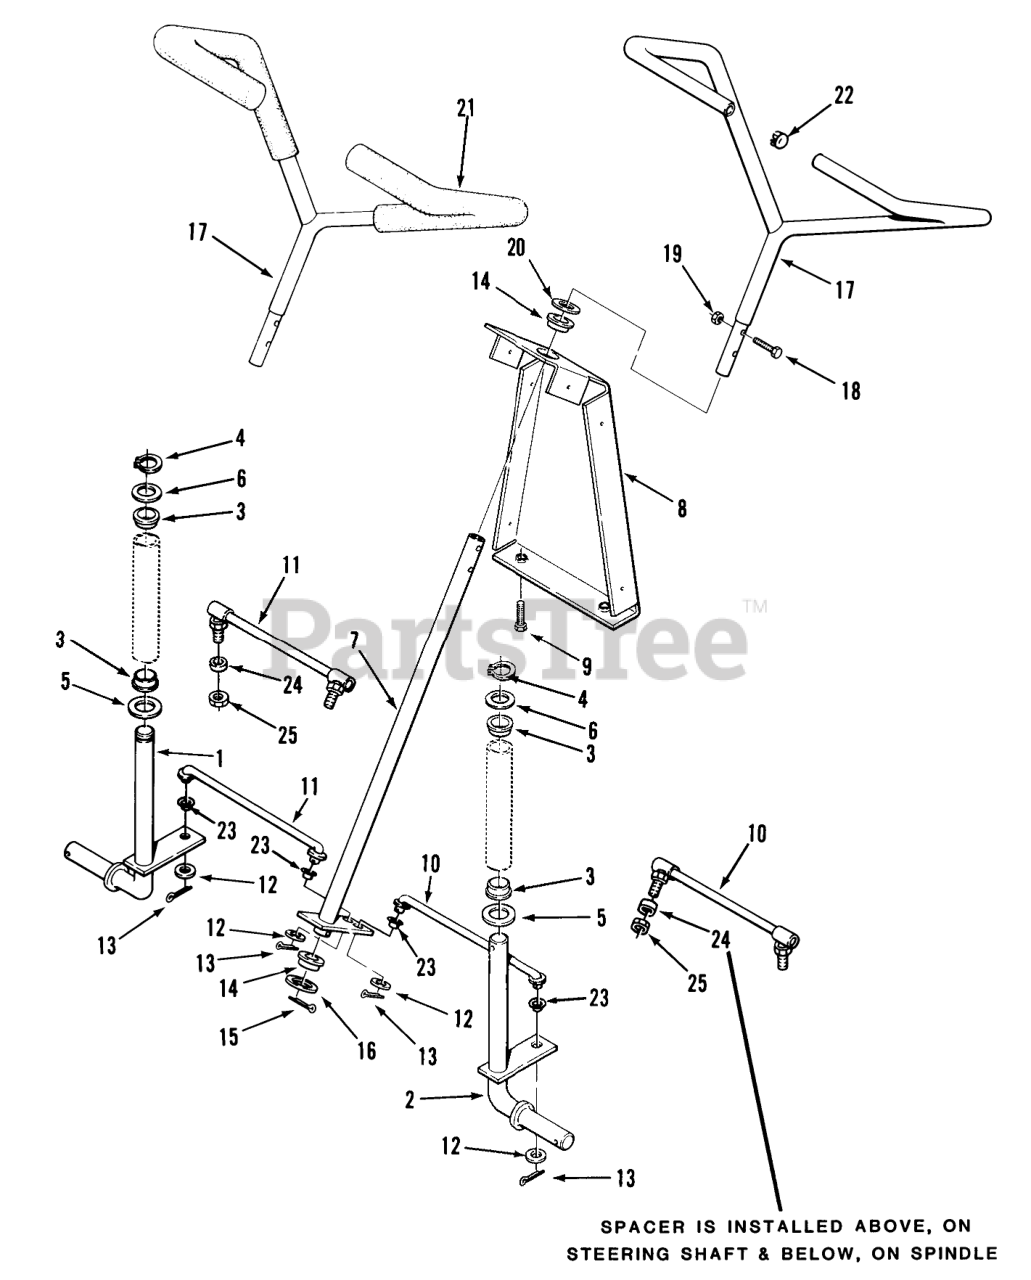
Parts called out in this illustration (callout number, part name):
1	ASS'Y-SPINDLE RH. R
2	FRONT SPINDLE ASSY LH R
3	BUSHING
4	Snap Ring
5	Washer
6	WASHER
7	ASSY STEERING SHA R
8	SUPPORT-STG UPPER B
9	Screw
10	TIE ROD LH R
11	TIE ROD RH R
12	Washer
13	Cotter Pin
14	BEARING
15	Cotter Pin
16	WASHER-FLAT
17	STEERING WHEEL
18	Bolt
19	Nut
20	Washer
21	Grips-Steering Wheel 112-6
22	PLUG BUTTON
23	BEARING
24	SPACER
25	NUT-6
